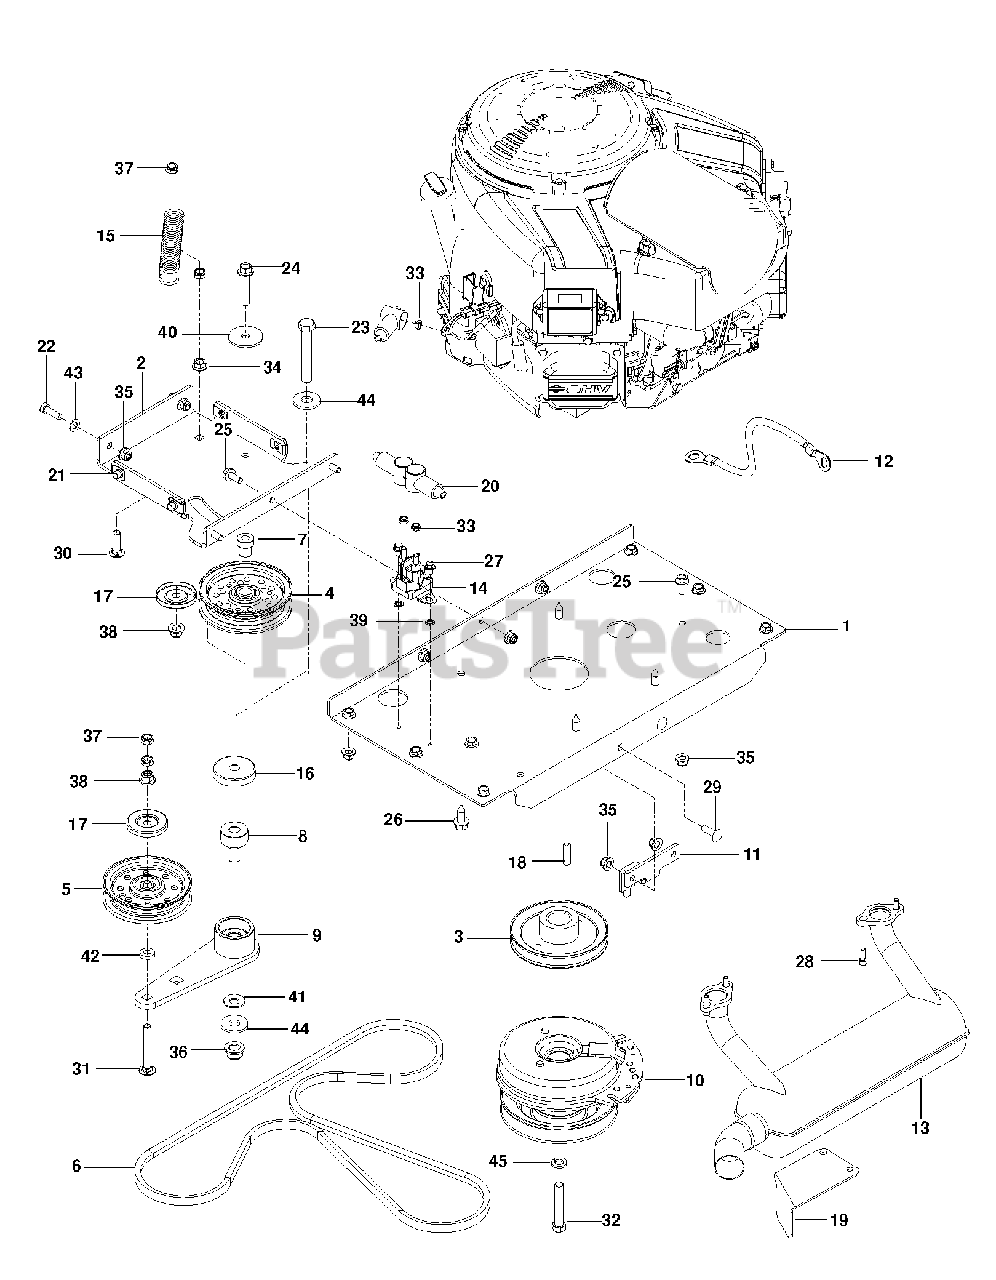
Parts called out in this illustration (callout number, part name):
2	PLATE, IDLER, BLK
3	PULLEY, V, 1.125 BORE
4	IDLER PULLEY
6	BELT, HYDRO, 3400
7	PIVOT, IDLER
8	PIVOT, BEARING
9	ARM, IDLER, STEEL, W/BGS
10	CLUTCH 200 FT LB
12	CABLE POSITIVE
13	MUFFLER, B&S CYCLONIC
14	SOLENOID
15	SPRING, PUMP
16	SHIELD, DUST
17	DUST SHIELD
18	KEY, 1/4 SQ X 1 1/4
19	SHIELD MUFFLER
20	INSULATOR
21	U-CLIP 5/16-18 NUT RETAINER
22	HCS 5/16C X 1
23	HCS 1/2C X 3 1/4
24	HHFS 3/8-16 X 2.0 GD 5
25	HHFS 5/16-18 X 3/4
26	HHFS 3/8-16 X 1.0 THD FORMING
27	HWST 1/4C X 3/8
29	RHSSNB 5/16C X 1.0
30	RHSNB 3/8-16 X 1-1/4
31	RHSNB 3/8-16 X 2.75
32	BOLT 7/16F X 2 1/2
33	JAM NUT 1/4C
34	NUT 3/8C WHIZ
35	5/16-18 NYLOC FLANGE NUT
36	NUT, 1/2-13 HEX FLG NYLOC ZD
37	NUT HEX 3/8-16 NYLON, THIN
38	NUT 3/8-16 HEX FLG NYLOC ZD
39	WASHER 1/4 INT TOOTH
40	WASHER, 3/8 SPEC
41	CONTACT BELLSPR 1/2
42	WASHER 3/8 X 3/4 X .187 TK
43	FLAT WASHER 5/16 SAE
44	WASH USS FLAT 1/2
45	WASHER 7/16 LOCK
